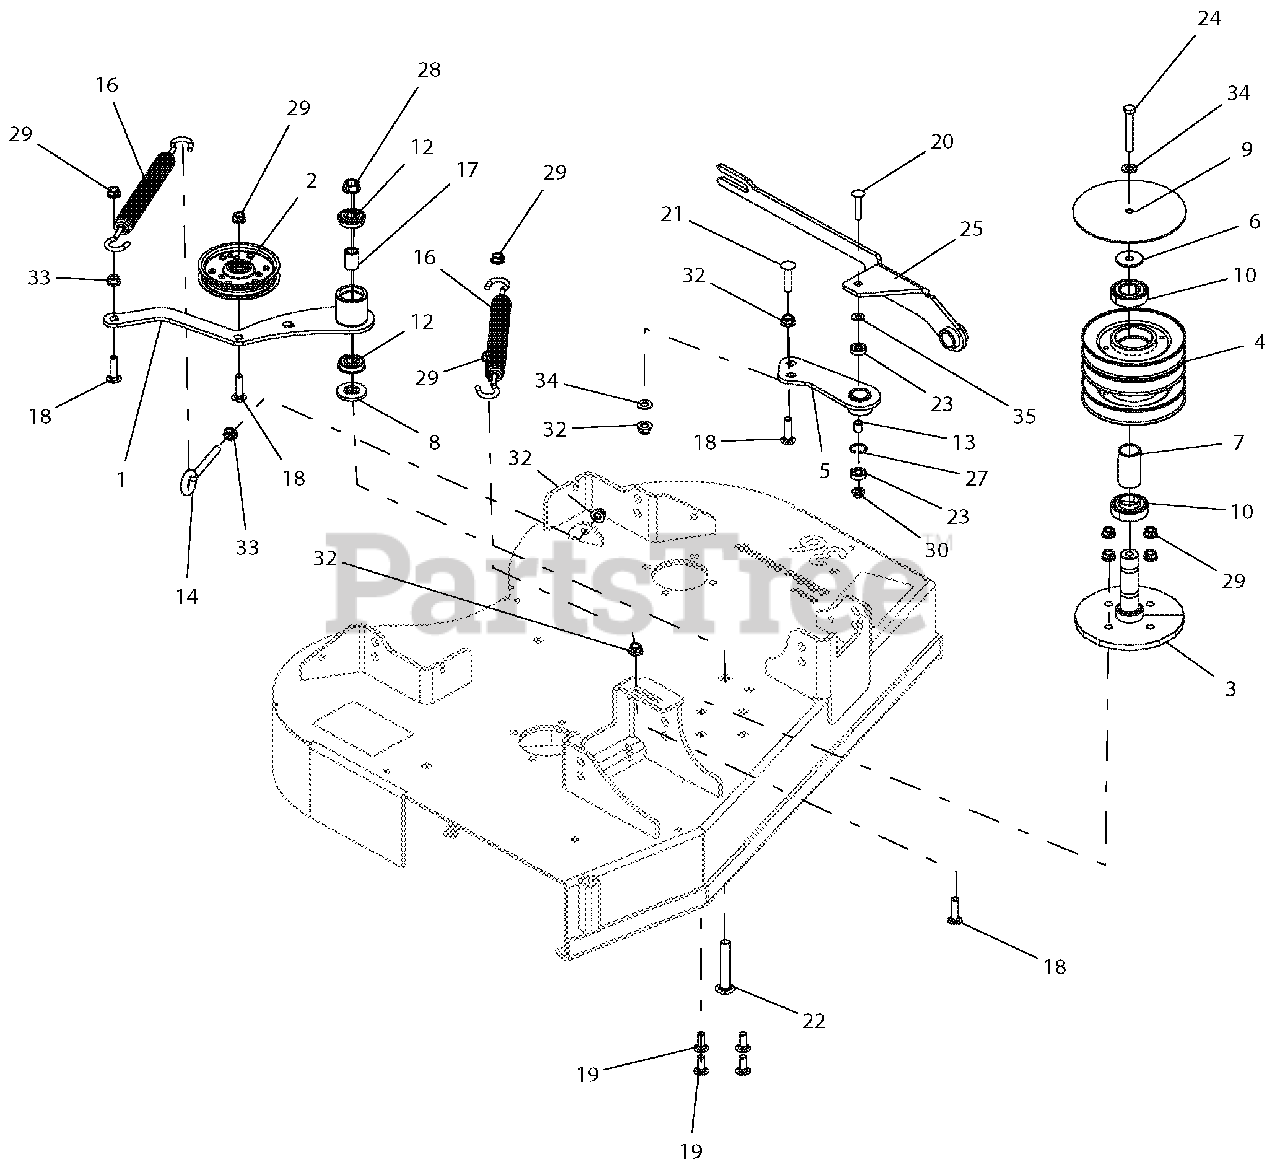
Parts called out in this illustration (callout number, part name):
1	WLDMT, IDLER DECK DRIVE
2	ASM, IDLER 4"
3	WLDMT, JACKSHAFT BASE
4	WLDMT, JACKSHAFT HOUSING
5	WLDMT, IDLER ARM
6	RETAINER, JACKSHAFT SPINDLE
7	SPCR, BRG SPINDLE
8	SPACER, IDLER ARM
9	PLATE, JACKSHAFT COVER-BLACK
10	BRG., RG 1.00 X 2.0467 X .591
12	BRG, BALL .501 X 1.38 X .438 SEALED
13	BSHG, SLV .330X.455X.550
14	BOLT, EYE .38-16X4.50 .75 DIA
16	SPRG, EXTENSION
17	SPACER, .510 X .750 X 1.148
18	BLT-RDHDSQNK .38-16X1.50 G5 Y
19	BLT-RDHDSQNK .38-16X1.00 G5 YWZC
20	BLT-RDHDSQNK .31-18X1.75 G5 YWZC
21	BLT-RDHDSQNK .38-16X1.75 G5 YWZC
22	BLT-RDHDSQSHNK .50-13X3.25 YWZC
23	BRG-BALL .315X.866X.276 (608)
24	BLT-HEX .38-16X2.75 GR8 YWZC
25	WLDMT, PIVOTING IDLER
27	RING, RETAINING-INTERNAL .875"
28	NUT-LK-CTR-FLG .50-13 YWZC
29	NUT, LK-CTR-FLG .38-16 YWZC
30	NUT, LK-CTR-FLG .31-18 YWZC
32	NUT-LK-NYL-FLG .38-16 YWZC
33	@NUT-SPNLK-FLG .375-16 YWZC
34	WSHR-FL-STL.406X.812X.065YWZ
35	WSHR-FL-STL.344X.688X.065YWZC
